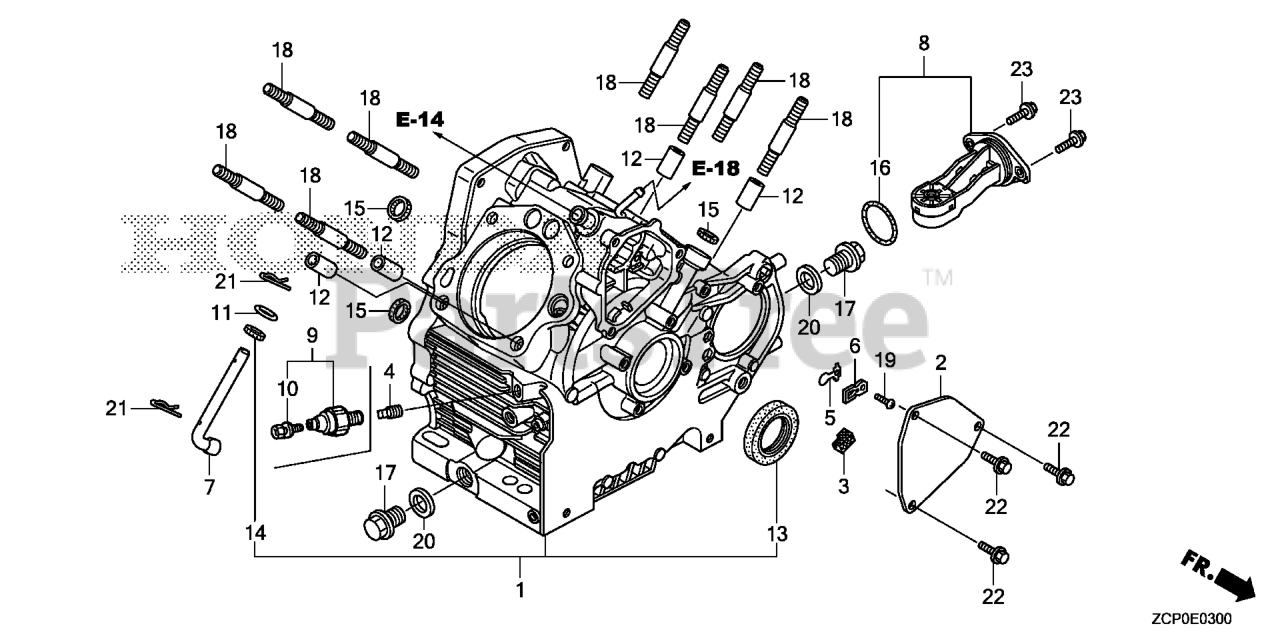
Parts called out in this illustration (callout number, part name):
1	CRANKCASE ASSY.
2	COVER, BREATHER
3	FILTER, BREATHER
5	VALVE, OIL OUTLET
6	PLATE, STOPPER
7	SHAFT, GOVERNOR ARM
9	SWITCH, OIL PRESSURE
10	SCREW-WASHER (4X8)
11	WASHER, PLAIN (10MM)
12	PIN, DOWEL (12X20)
13	OIL SEAL (38X58X9)
14	OIL SEAL (10X16X5)
15	GASKET, OIL PASSAGE
17	BOLT, DRAIN PLUG (20MM)
18	BOLT, STUD (10X40)
19	SCREW, PAN (3X8)
20	WASHER, DRAIN PLUG (20MM)
21	PIN, LOCK (10MM)
22	BOLT, FLANGE (6X14)
